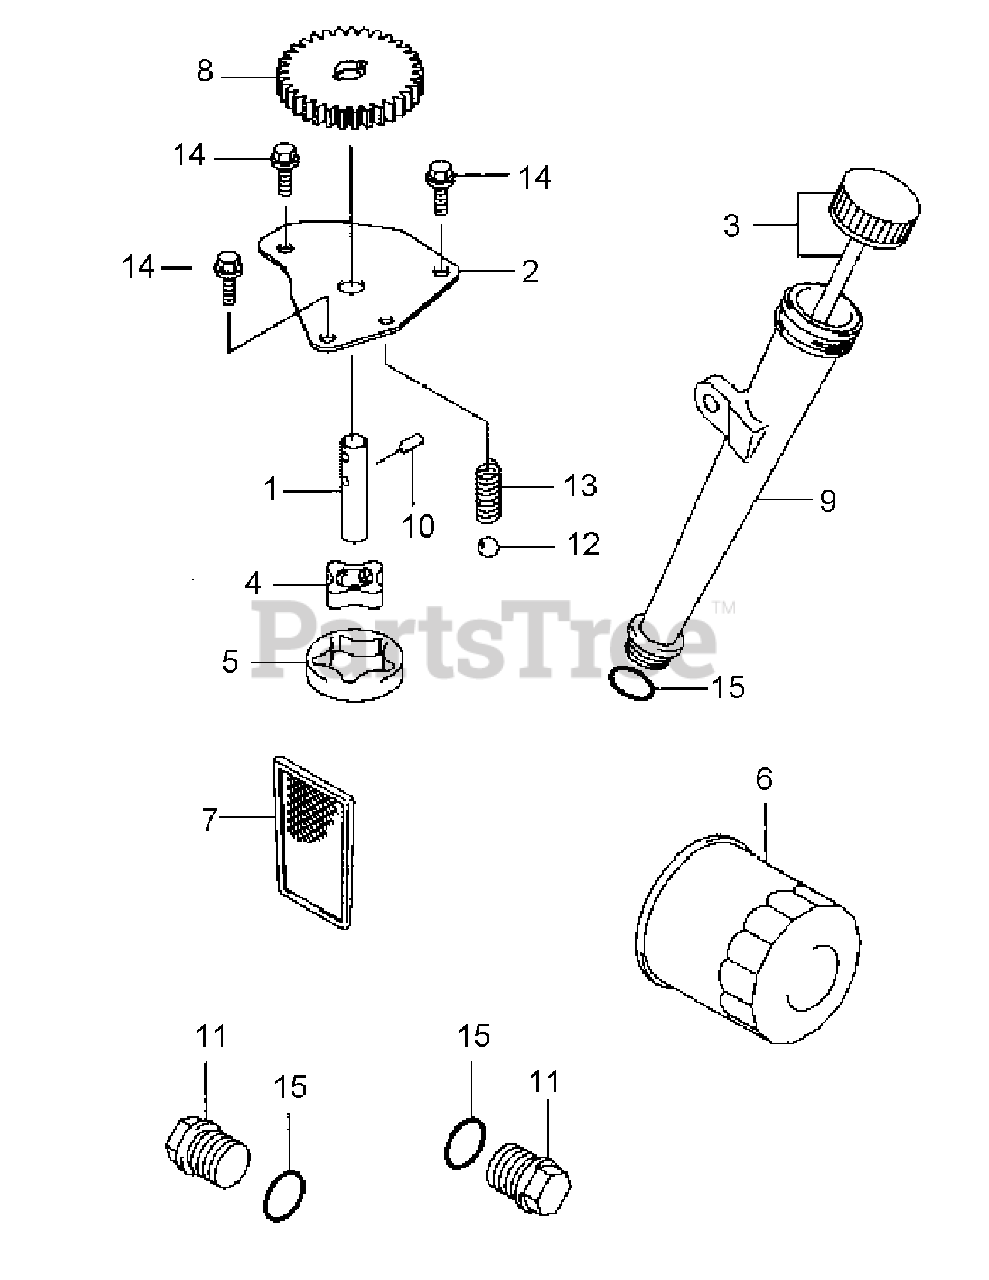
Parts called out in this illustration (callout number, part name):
1	SHAFT
3	CAP-ASSY
4	ROTOR-PUMP, IN
5	ROTOR-PUMP, OUT
6	FILTER-OIL
7	FILTER-OIL Screen
10	PIN
11	PLUG
14	BOLT-FLANGED
15	O RING, 16MM
